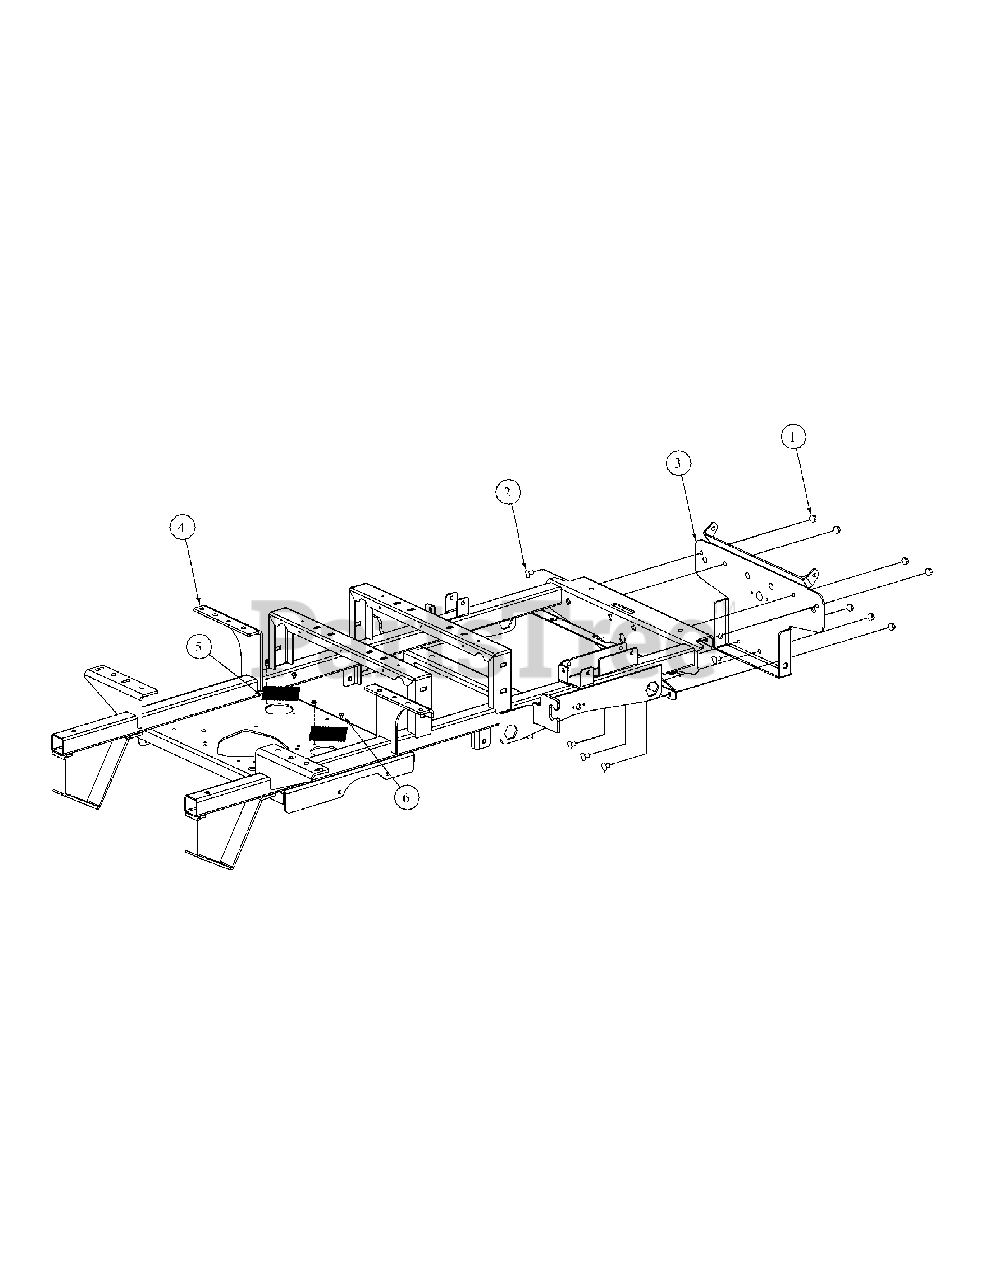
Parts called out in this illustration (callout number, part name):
1	Hex Nut, 3/8-16 Flange Lock
2	Carriage Bolt, 3/8-16 x .75 Long
3	Bracket Assembly, Frame, Front
3	MMZ 1848 Front Label
4	Frame Assembly
5	Cover, Hydro Fan
6	Screw, TT, 1/4-20, 0.5
